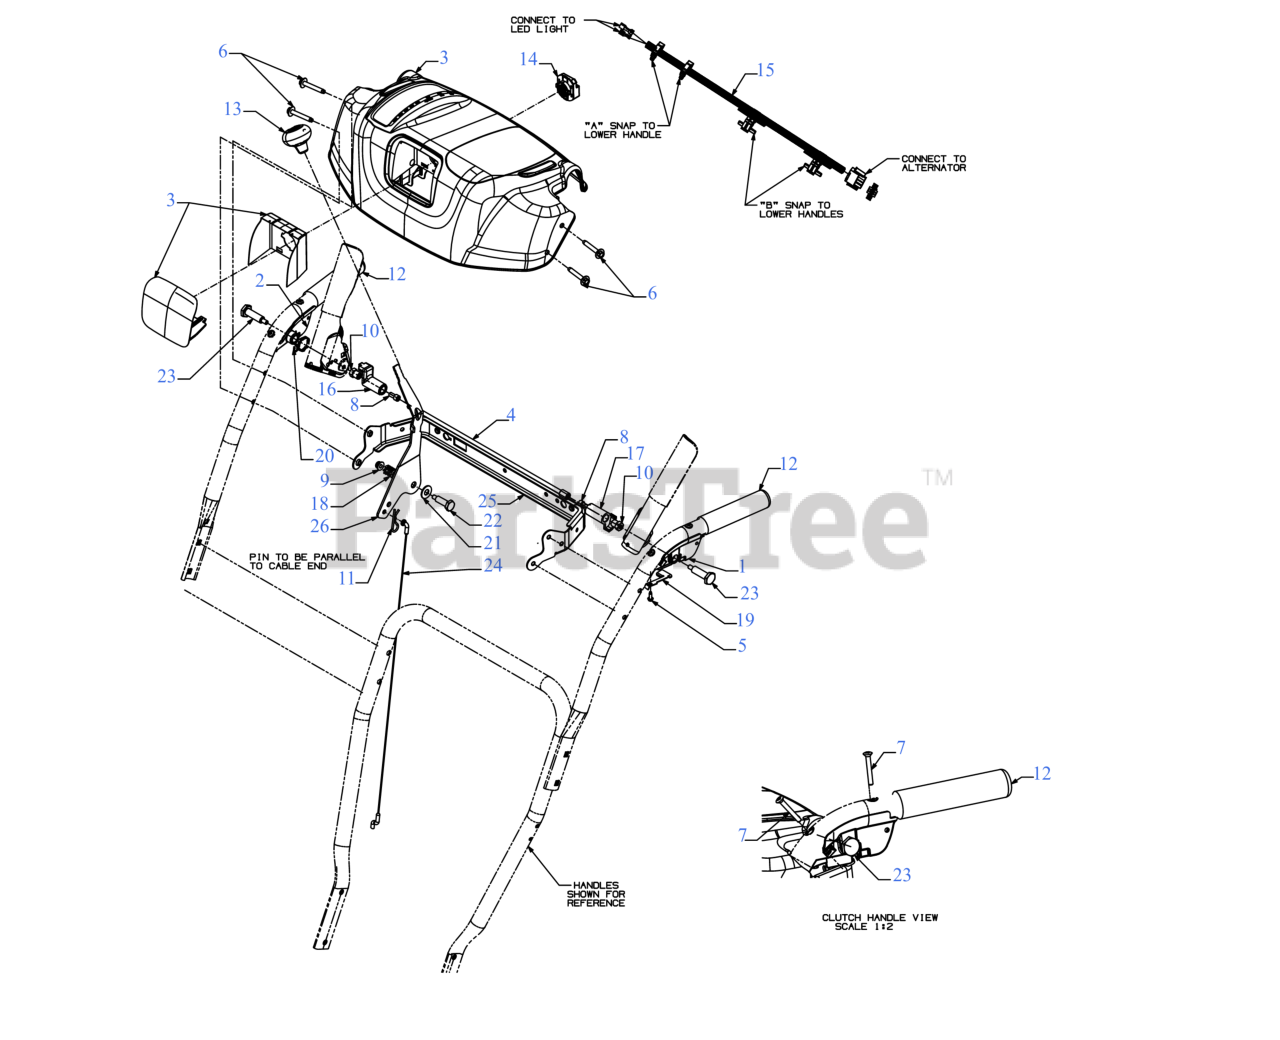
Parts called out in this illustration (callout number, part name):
1	CLUTCH LOCK HANDLE ASSEMBLY (LH)
2	CLUTCH LOCK HANDLE ASSEMBLY (RH)
3	HANDLE PANEL ASSEMBLY
4	PIVOT ROD
5	SCREW #8-16 x .50
6	SCREW 1/4-20 x 1.625
7	SCREW #10-24 x 1.375
8	SCREW 1/4-20 x .50
9	FLANGE LOCK NUT
10	HEX NUT W/PATCH
11	INTERNAL COTTER PIN
13	SHIFT KNOB
14	LED HEADLIGHT SOCKET (150 LUMNES)
15	LIGHT HARNESS
16	LOCK PLATE
17	CLUTCH LOCK CAM
18	COMPRESSION SPRING
19	CLUTCH SPRING
20	TORSION SPRING
21	FLAT WASHER .40X.88X.060
22	SHOULDER SCREW
23	SHOULDER SCREW .437 x 1.345 1/4-20
24	SPEED SELECTOR CABLE (PLASTIC)
25	HANDLE SUPPORT BRACKET (POWDER BLACK)
